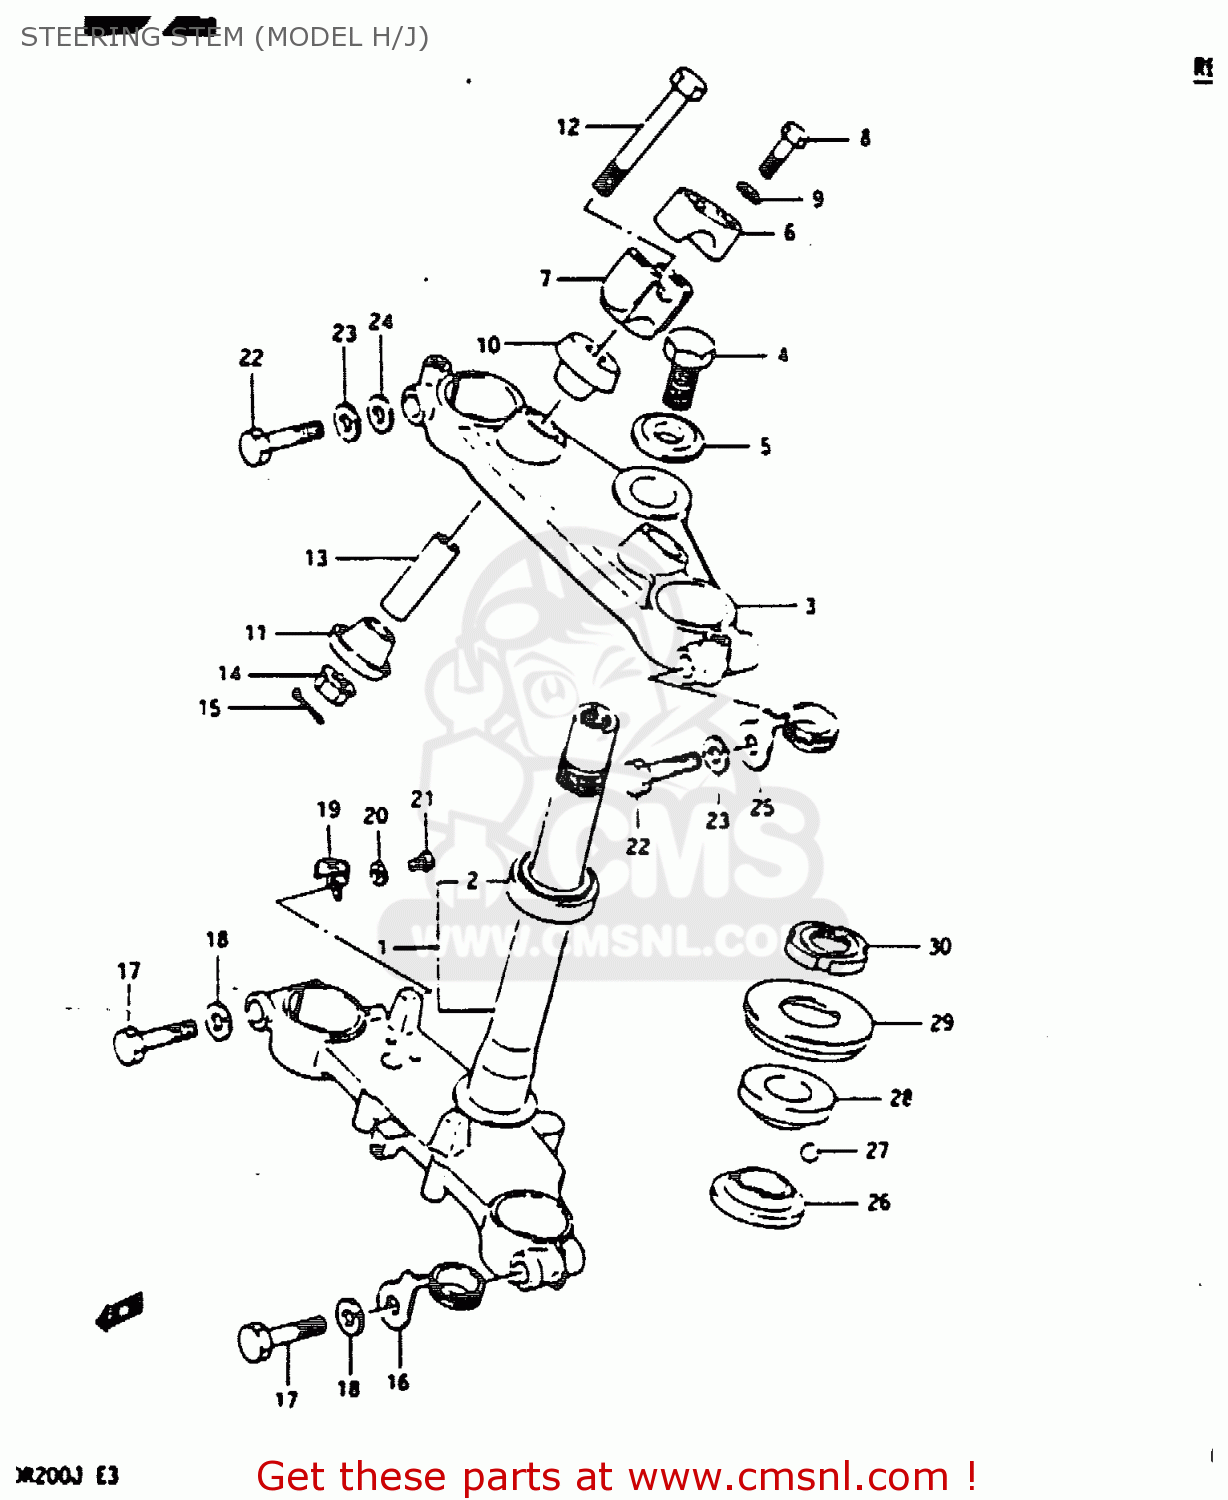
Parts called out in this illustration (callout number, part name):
1	STEM,STEERING
2	BEARING
3	HEAD,STEERING STEM
4	BOLT,STEERING STEM HEAD
5	WASHER
6	HOLDER,HANDLE UPR
7	HOLDER,HANDLEBAR LWR
8	BOLT
9	WASHER,LOCK,8.
10	RUBBER,HANDLE HOLDER
11	RUBBER,LWR
12	BOLT
13	SPACER
14	NUT
15	COTTER PIN
16	CLIP,UPPER
17	BOLT,INNER TUBE FITTING
18	WASHER,LOCK
19	CLIP
20	WASHER,LOCK
21	SCREW
22	BOLT,INNER TUBE FITTING
23	WASHER,LOCK
24	WASHER 10MM
25	CLIP,UPPER
26	RACE,STEERING INNER (SUJ)
27	BALL
28	RACE,STEERING,OUTER,UPPER
29	SEAL,STEERING UPR DUST
30	NUT,STEERING STEM
